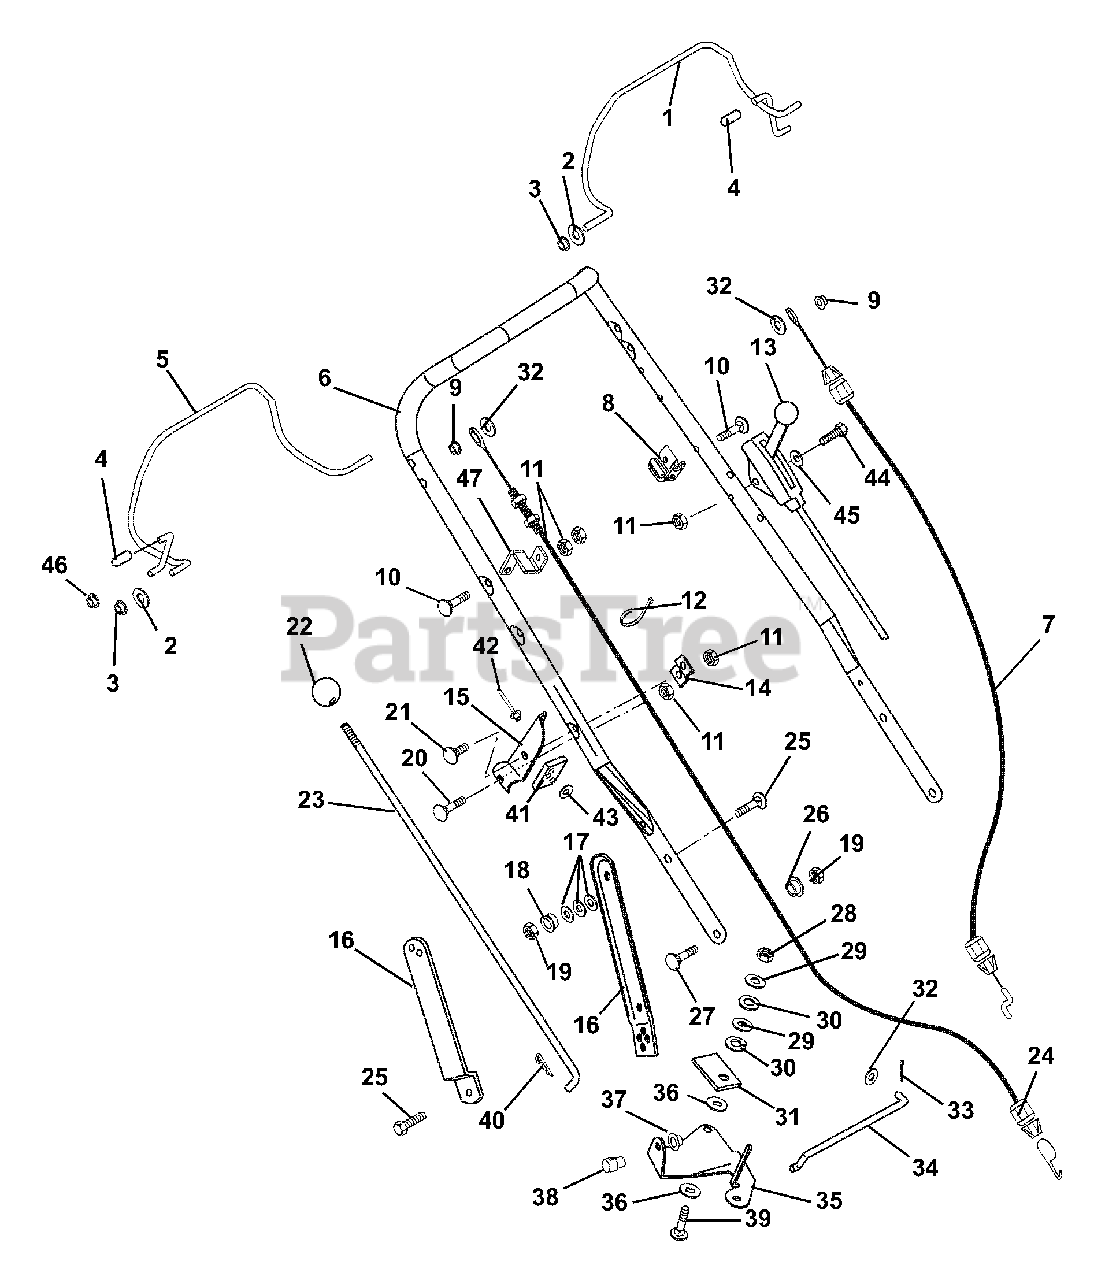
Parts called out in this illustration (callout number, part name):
1	BAIL, ENGINE WELDMENT
2	@WSHR-FL-STL.344X.688X.065YWZC
3	BSHG-FLG .325X.444X.440X.560
4	CAP, VINYL, .25 ID
5	BAIL, TRACTION (WLDMENT)
6	BAR, WBLM HANDLE
7	CABLE, ENGINE (BRIGGS/GXV)
7	CABLE, WBLM ENGINE
7	CABLE, ENGINE
7	CABLE, ENGINE - ADJUSTABLE
8	ANCHOR, WBLM ENGINE CABLE
9	PUSH NUT, .25
9	RG-RTNG-EXT .250X.010
10	BLT-RDHDXLSQNK.25-20X1.25 G5ZC
11	@NUT-LK-CTR .25-20 YWZC
12	CABLE TIE LG 5-1/2
13	CABLE, LOCKOUT CONTROL
13	CONTROL - THROTTLE - HONDA
14	BRACE, SPEED CONTROL
15	BRACKET, SPEED CONTROL
16	LINK, HANDLEBAR ADJUSTMENT LH
16	LINK, HANDLEBAR ADJUSTMENT RH
16	BRACKET, HANDLEBAR
17	WASHER, BELLEVILLE YWZC
18	BSHG-FLG .325X.500X.513X.875
19	@NUT-LK-CTR .31-18 YWZC
20	@BLT-RDHDSQNK .25-20X1.50 G5YZ
21	@BLT-RDHDSQNK .25-20X.50 G5YZ
22	KNOB, BALL 5/16-18 X 1.5
23	ROD-SPEED CONTROL
24	CABLE, WBLM TRACTION
25	@BLT-RDHDSQNK .31-18X1.00 G5YZ
25	@BLT-HEX .31-18X.75 GR5 YWZC
26	BSHG, FLG .325X.499X.26X.88
27	@BLT-RDHDSQNK .31-18X.75 G5YZ
27	@BLT-RDHDSQNK .31-18X1.00 G5YZ
28	@NUT-LK-CTR .38-16 YWZC
29	@WSHR-FL-STL.406X.812X.065 YWZ
30	WSHR-LK .375X.115 HVY YWZC
31	PRESSURE FLANGE
32	@WSHR-FL-STL.281X.62X.065 YWZC
33	@PIN-CTR .06X.50 EXTPRSQCT YWZ
34	SHIFT LINK
35	BELL CRANK - SPEED CONTROL
36	FRICTION WASHER
37	CAP, 3/8 ROD YWZC
38	SWIVEL
39	@BLT-RHDSSQNK .38-16X1.25 G5YZ
40	PIN-HAIR INT .08X.18X1.18 YWZC
41	SUPPORT PAD
42	RVT .187X.575 DOME AL BLACK
43	@WSHR-FL-STL.219X.50X.049 YWZC
44	BLT-RDHDSQNK .25-20X1.75 G5YZ
45	@WSHR-FL-STL.250X.56X.049 YWZC
46	NUT-PUSH .312 DIA. PAL
47	ANCHOR, CABLE
